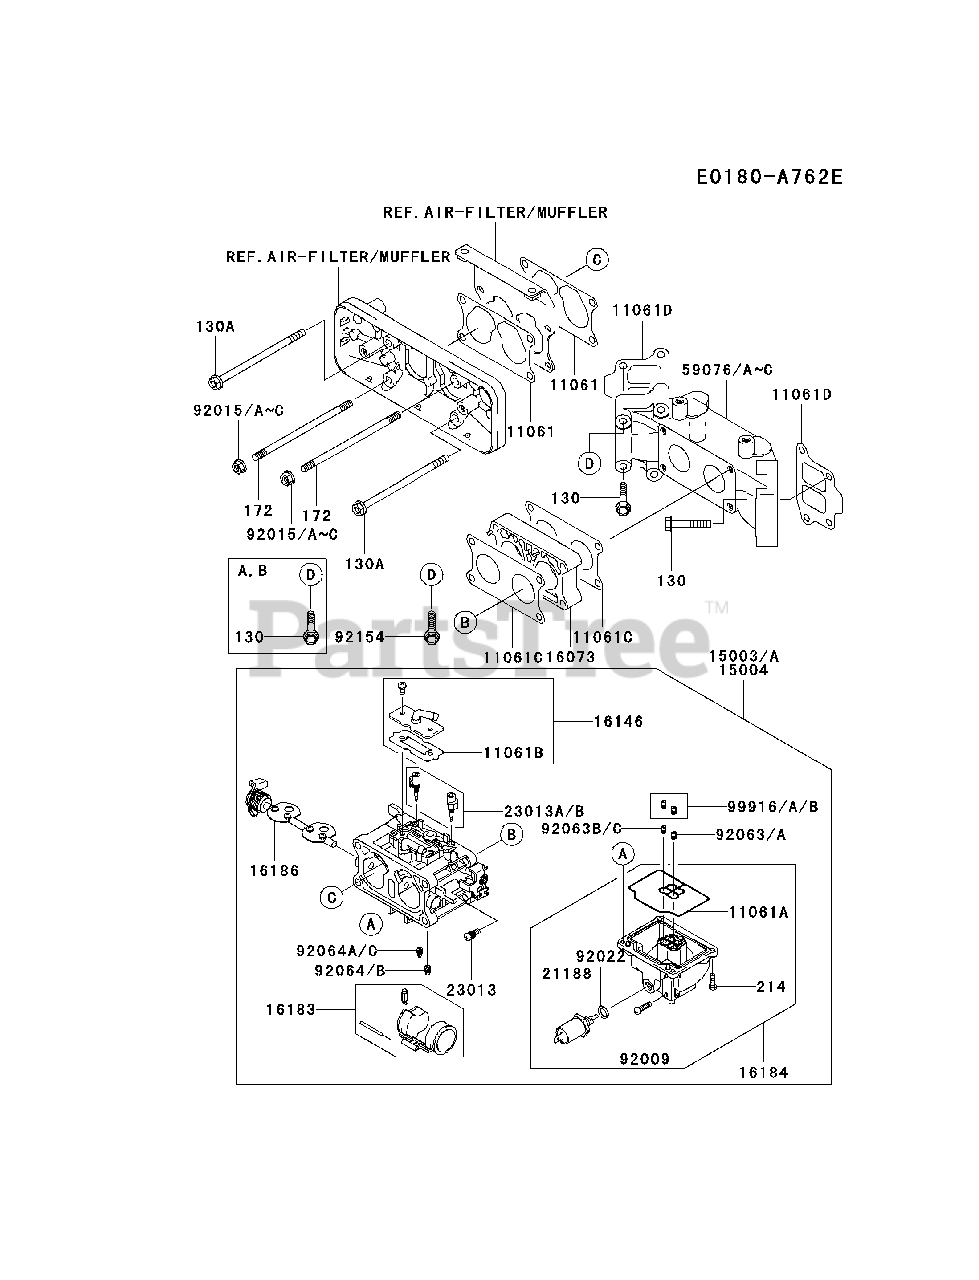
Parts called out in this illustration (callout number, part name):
130	BOLT-FLANGED,6X35
130A	BOLT-FLANGED,6X110
172	BOLT-STUD,6X110
214	SCREW-PAN+-,4X14
